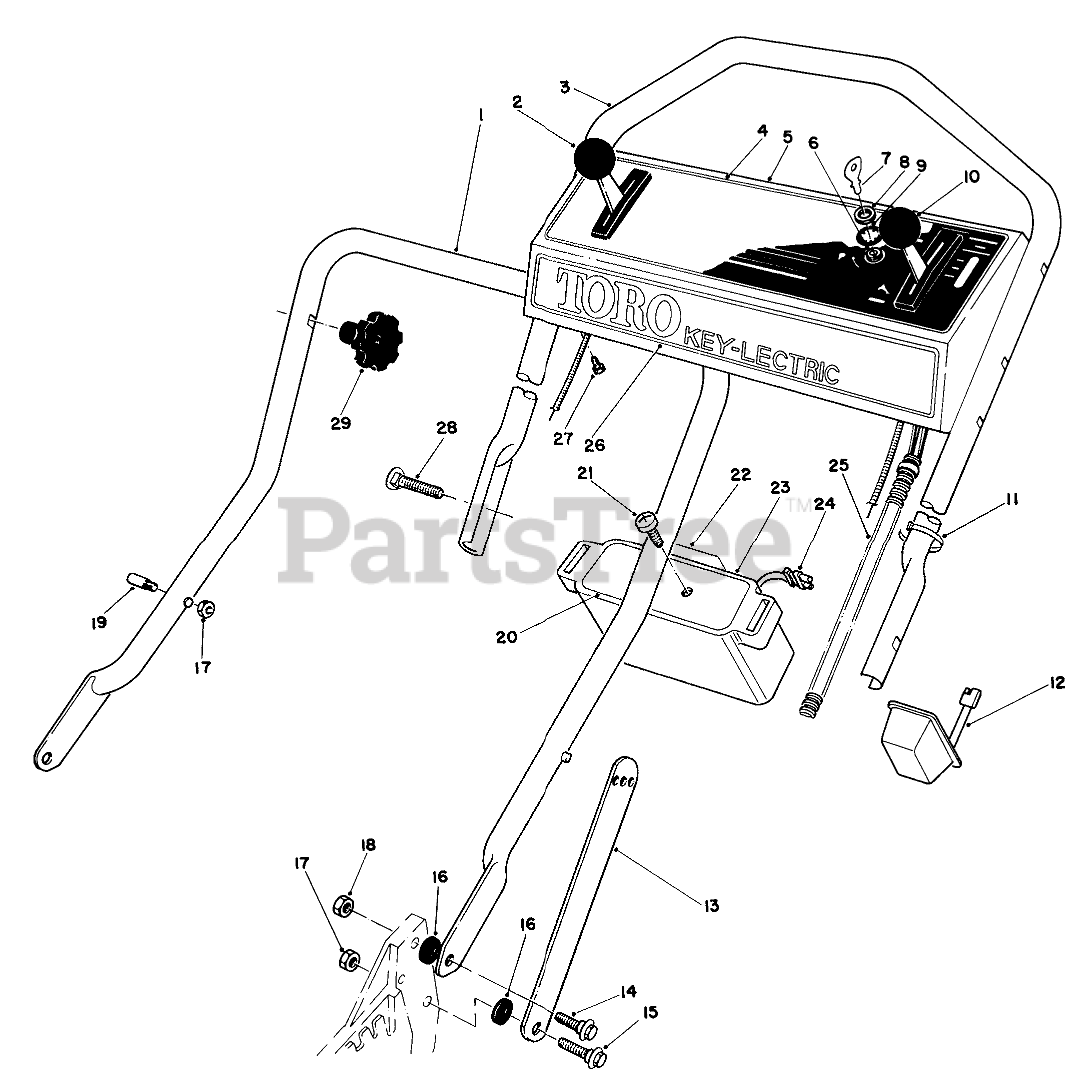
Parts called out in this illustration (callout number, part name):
1	Handle-Lower
2	GROUND SPEED CONTROL
3	Handle-Upper
4	OBS INSTR PANEL DECAL
5	Control Panel (Incl. Ref. #4)
6	STARTER SWITCH ASM
7	Key
8	NUT-HH
9	WASHER-TOOTH, INTERNAL
10	SERVICE THROTTLE CONTRO
11	TIE-CABLE
12	Charger
13	Handle Latch
14	SCREW-SHOULDER
15	SCREW-SHOULDER
16	SPACER
17	NUT-LOCK, NI
18	NUT-LOCK, NI
19	HANDLE PIN
20	BATTERY COVER
22	Decal
23	Battery Case
24	Plug & Wire Assembly
25	Wire Harness
26	Decal-Toro
27	SCREW-HWHTF
28	5/16-18 X 2 HNDLE SCREW
